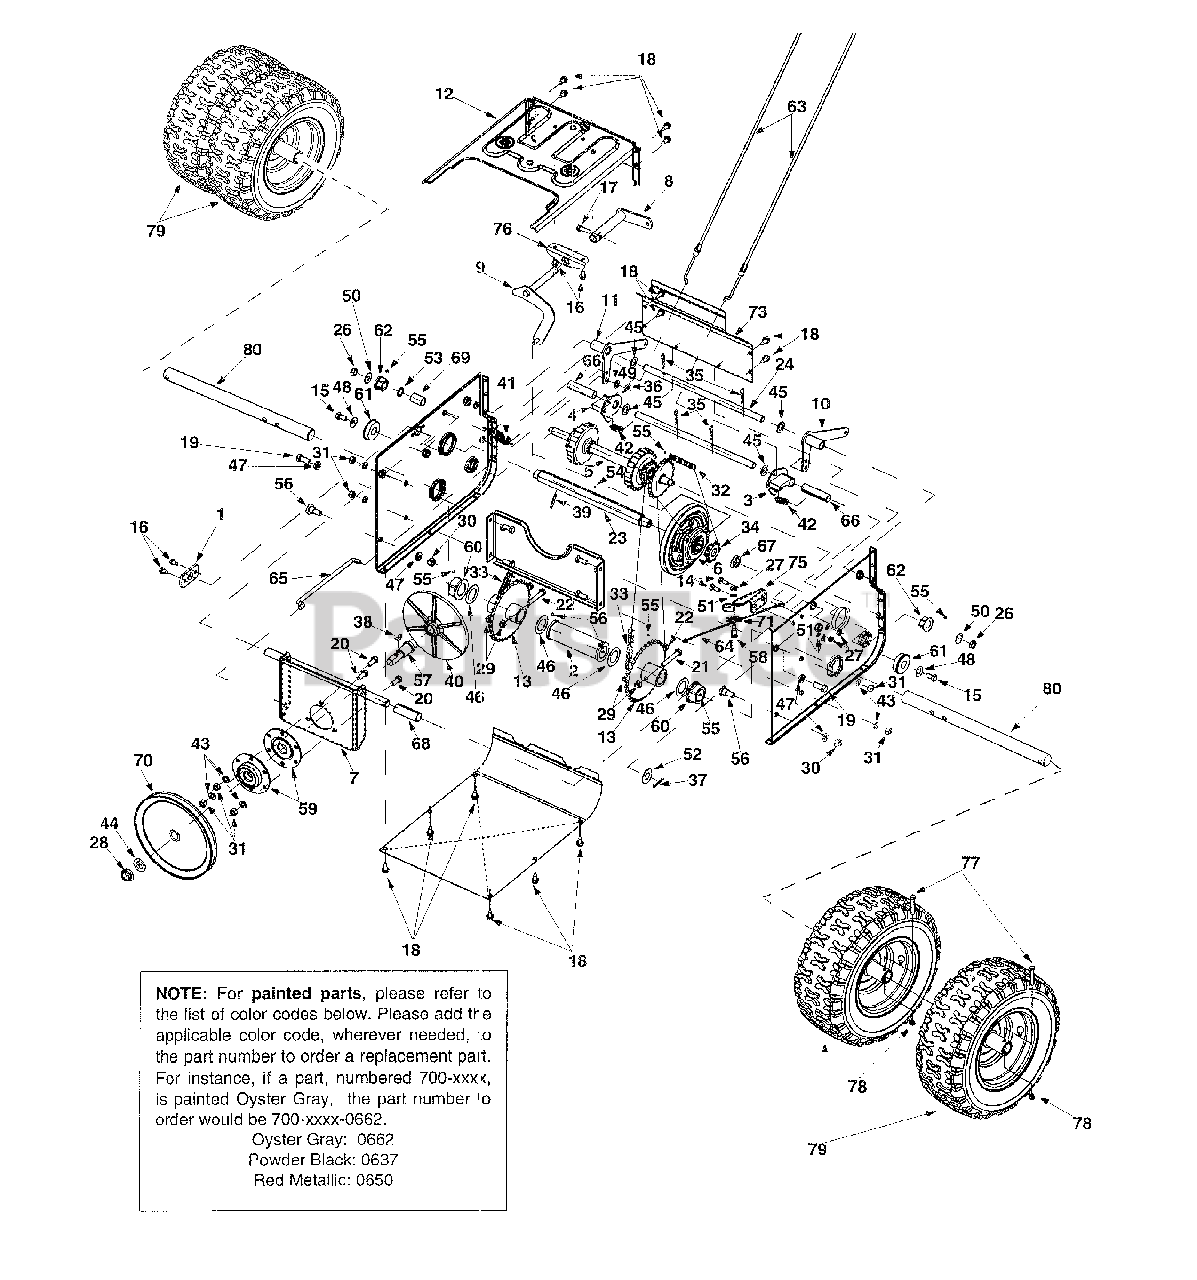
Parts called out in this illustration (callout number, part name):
1	Support Bracket: Pivot
2	Bush Assembly
3	Dogg Assembly LH
4	Dogg Assembly RH
5	Shift Assembly
6	Wheel Bearing Assembly
7	Support Bracket Assembly
10	Auger Actuator Bracket Assy.
11	Drive Actuator Bracket Assy.
14	Hex Screw 1/4-28 x .625"
15	Hex Screw 5/16-18 x .625"
16	TT Screw 1/4-20 x .5"
17	TT Screw 1/4-20 x 1"
18	TT Screw 1/4-20 x .625"
19	Hex Screw 3/8-16 x .880"
20	Hex Screw 5/16-18 x .75"
21	Hex Screw 5/16-18 x 2"
22	Hex Screw 5/16-18 x 1.75"
23	Hex Shaft: Drive
24	Actuator Shaft
25	Actuator Drive Shaft
26	Lock Nut
27	Hex Nut 1/4-28
28	Jam Lock Nut
29	Hex Lock Nut
30	Hex Nut 3/8-16
31	Hex Nut 5/16-18
32	Chain
33	Chain
34	Sprocket
35	Hairpin Clip
36	Hairpin Clip
37	Cotter Pin
39	Roll Pin
40	Drive Plate
41	Extension Spring
42	Extension Spring
43	Lock Washer 5/16
44	Lock Washer 5/8
45	Flat Washer
46	Flat Washer
47	Lock Washer
48	Beleville Washer
49	Flat Washer
50	Flat Washer
51	Lock Washer
52	Flat Washer
53	Flat Washer
54	Lubricant
55	Grease
56	Shoulder Screw
57	Spindle: Drive Plate
58	Shoulder Screw 1/4-28 x .375"
59	Bearing Housing Assembly
60	Flange Bearing
61	Ball Bearing
62	Hex Flange Bearing
63	Steer Cable
64	Idler Cable: Auger
65	Clutch Rod: Drive
66	Split Spacer
67	Spacer
68	Split Spacer
69	Spacer
70	Drive Pulley
71	Roller Cable
72	Frame Support Bracket
77	Hex Screw 5/16-18 x 2"
78	Lock Nut
80	Axle: Wheel
